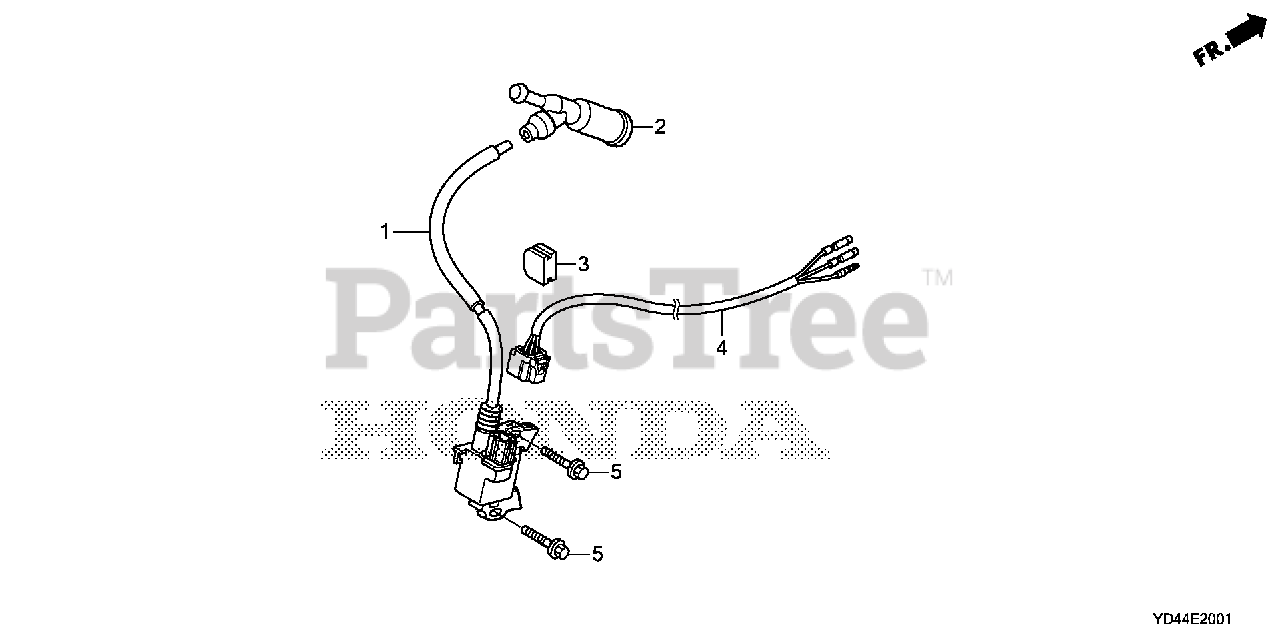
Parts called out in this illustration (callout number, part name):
1	COIL ASSY., IGNITION
1	COIL ASSY., IGNITION (IIDA)
2	CAP ASSY., NOISE SUPPRESSOR (NGK Y-EZD)
3	GROMMET, WIRE
4	WIRE HARNESS ASSY., ENGINE
5	BOLT, FLANGE (6X28) (CT200) Use up to Engine SN 1530314.
